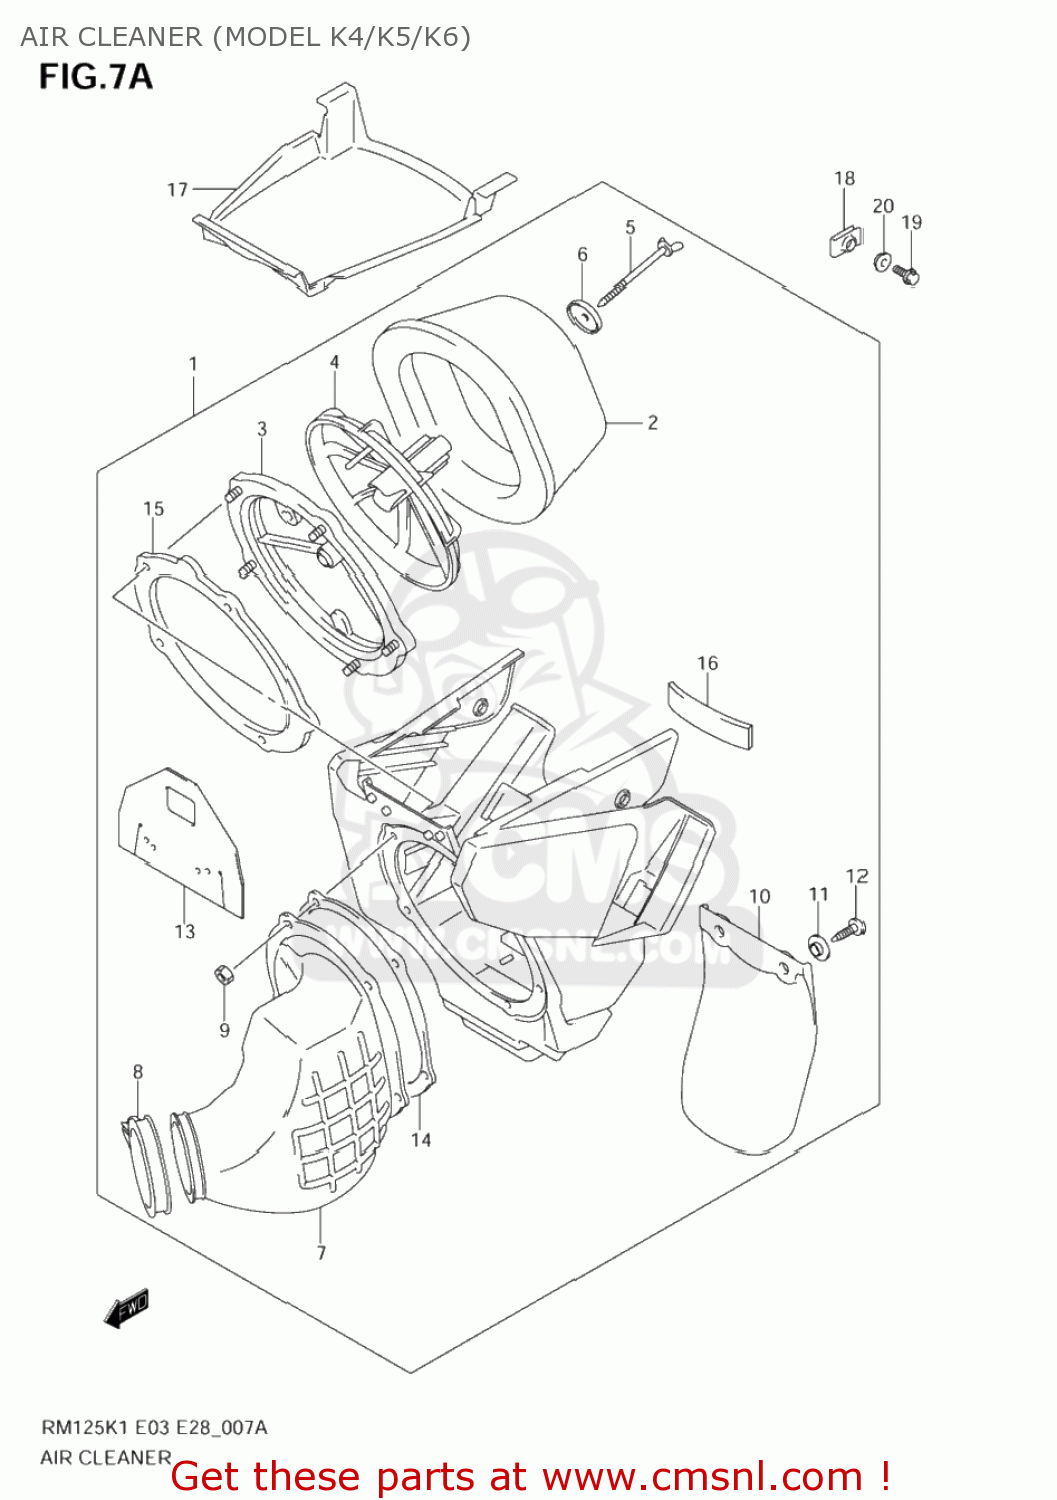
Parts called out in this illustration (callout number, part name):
1	CLEANER ASSY,AIR
2	FILTER ASSY
3	BASE,FILTER
4	HOLDER,FILTER
5	BOLT,WING
6	WASHER,AIR CLEANER
7	TUBE,OUTLET
8	CLAMP
9	NUT
10	MUDGUARD
11	COLLAR
12	SCREW
13	COVER,AIR CLEANER
14	PLATE
15	GASKET (NAS)
16	CUSHION,AIR CLEANER
17	CAP,AIR CLEANER
18	HOLDER,REAR BU
19	BOLT(6X10)
20	WASHER
